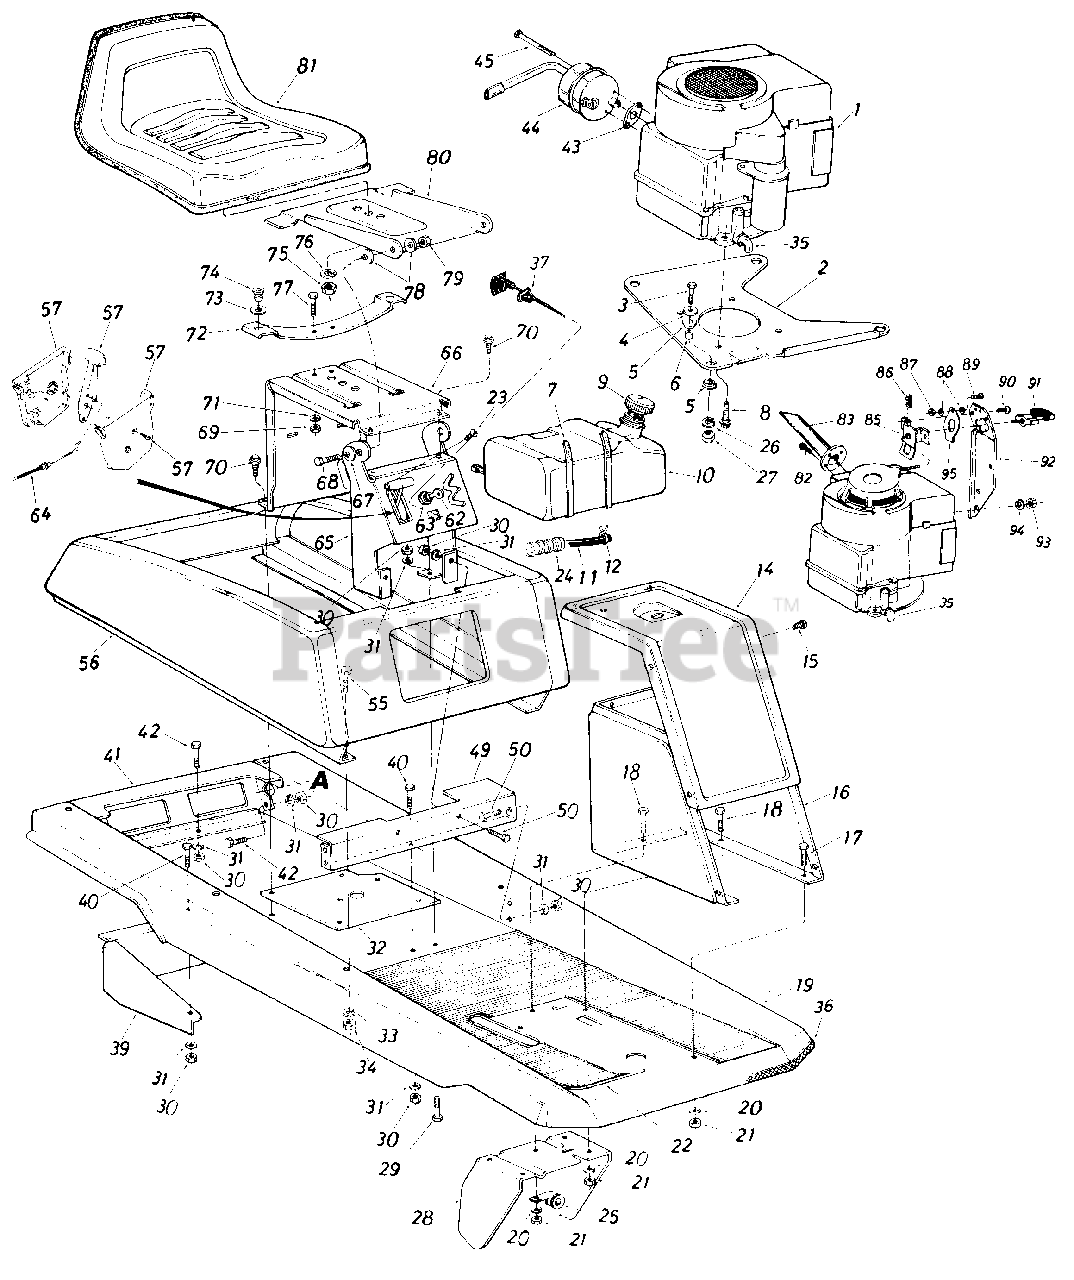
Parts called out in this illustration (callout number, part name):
1	Engine
2	Engine Mounting Plate
3	Hex Bolt 5/16-24 x 1.25" Lg.
4	Fl-Wash. .330" I.D. x 1.125" O.D.
5	Engine Mounting Grommet
6	Spacer .315" I.D. x .50" O.D. x 520 Lg
7	Cable Tie 30.6 Lg.
8	Hex Wash. Hd. Self-Tap Scr. 3/8-16 x 1.25" Lg.
9	Gas Gauge
10	Fuel Tank
11	Gas Line
12	Hose Clamp-.406" Dia.
22	Floor Mat
23	Truss Mach. AB-Tap Scr. #10 x .50" Lg.
24	Convoluted Conduit
25	Clamp
26	L-Wash. 5/16" I.D.*
27	Hex Nut 5/16-24 Thd.
28	Clutch-Brake Pedal Ass'y.
29	Hex Bolt 5/16-18 x .75" Lg
30	Hex Nut 5/16-18 Thd.
31	L-Wash. 5/16" I.D.
32	Mounting Brkt. Variable Speed Pulley
33	L-Wash. 1/4" I.D.
34	Hex Nut 1/4-20 Thd.*
35	90ø Elbow Male To Female
36	Trim Strip 18" Lg.
37	Choke Control
39	Transaxle Support Ass'y.
40	Hex Bolt 5/16-18 x .75" Lg.
43	Exhaust Gasket
44	Muffler Ass'y.
45	Shld. Bolt
49	Seat Support & Frame Brkt.
50	Hex Bolt 5/16-18 x .75" Lg.*
55	Hex Bolt 1/4-20 x .50" Lg.
57	Throttle Control Box Ass'y. (5 H.P)
62	Ignition Key
63	Ignition Switch (Electric Start)
64	Throttle Control Wire-35"
65	Front Seat Bracket
66	Rear Seat Bracket
67	Bell-Wash. .345" I.D. x .88" O.D.
68	Hex Bolt 5/16-18 x .75" Lg.
69	Hex Nut 5/16-18 Thd.*
70	Hex Self-Tap Scr. 5/16-18 x .75" Lg.
71	L-Wash. 1/4" I.D.
72	Seat Spring
73	Fl-Wash. .531" I.D. x .930" O.D.
74	Grommet
75	Hex Nut 1/2-13 Thd.
76	L-Wash. 1/2" I.D.*
77	Hex Bolt 1/4-20 x .75 Lg.
78	Bell-Wash. .345" I.D. x .88" O.D.
79	Hex Cent. L-Nut 5/16-18 Thd.
80	Seat Pivot Bracket
81	Seat Ass'y. Comp.
82	Hex Wash. Hd. TT-Tap Scr. 8-32 x .50" Lg.
83	Exhaust Pipe Ass'y.
85	Switch Brkt. Assy.
86	Speed Nut #10-24 U-Type
87	Hex Nut #10-24 Thd.
88	Fiber Washer
89	Truss Mach. Scr. #10 x .50" Lg.
90	Truss Mach. Scr. #10 x .50" Lg.*
91	Plastic Handle
92	Rope Handle Bracket
93	Hex Nut 5/16-18 Thd.*
94	L-Wash. 5/16" I.D.
95	Switch Spring
